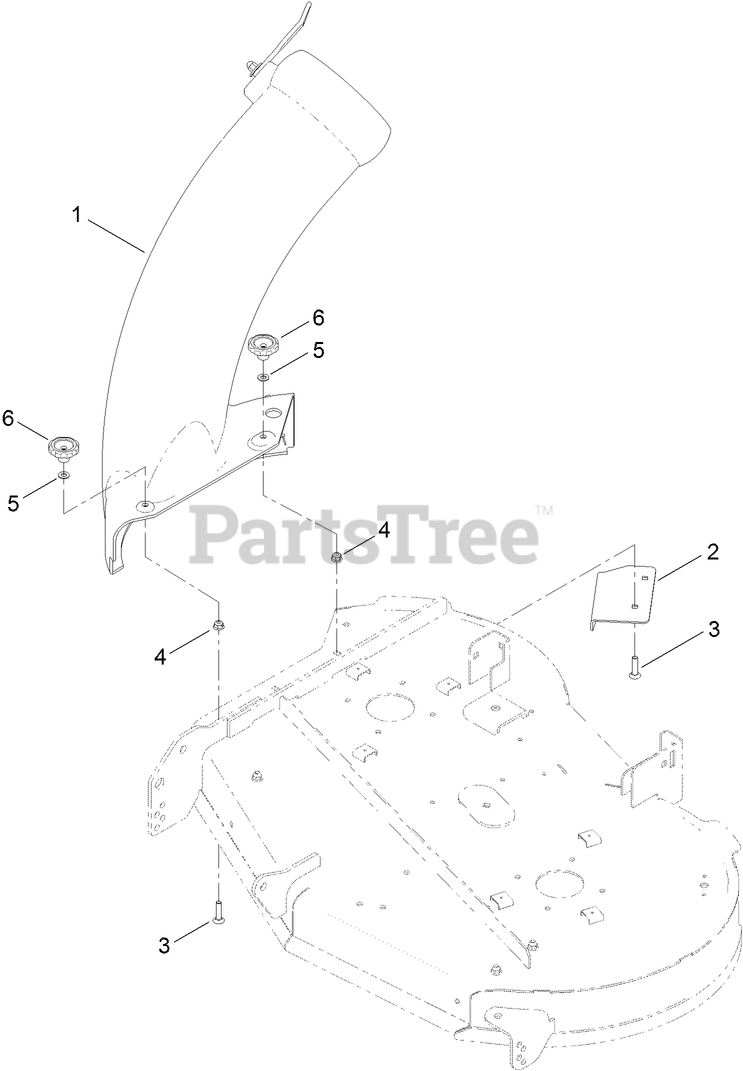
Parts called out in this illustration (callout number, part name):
1	CHUTE ASM
2	BAFFLE-CUTOFF
3	SCREW-CARR
4	NUT-HF, NI
5	WASHER-PLAIN
